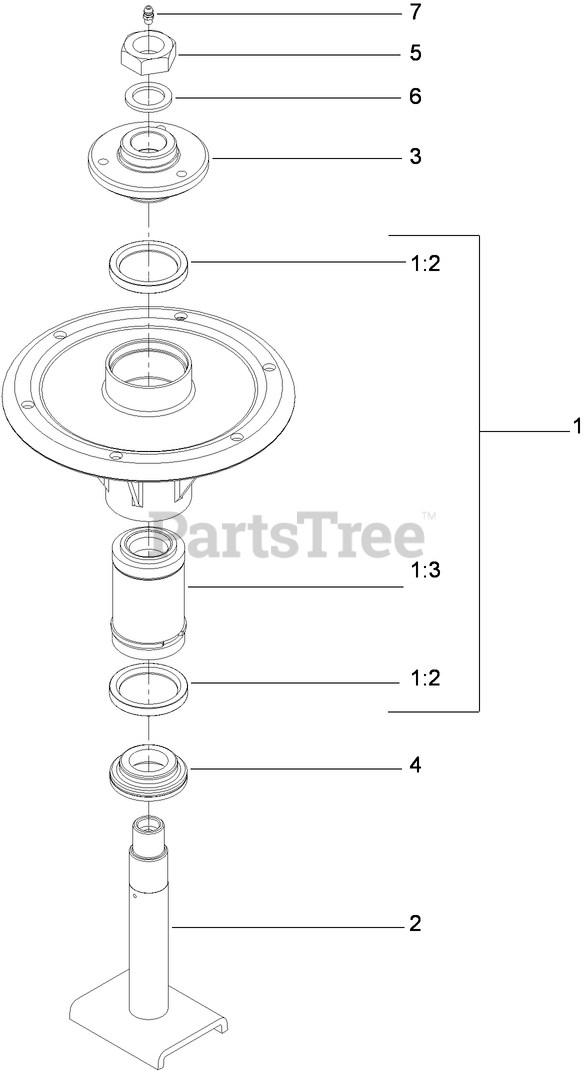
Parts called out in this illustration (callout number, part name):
1	SPINDLE BEARING ASM
1:2	SEAL-OIL
1:3	BEARING/SPACER KIT
2	SPINDLE SHAFT ASM
3	HUB-SPLINE
4	SPACER-SHAFT, SPINDLE
5	NUT-LOCK, NI
6	WASHER-THRUST
7	FITTING-GREASE
